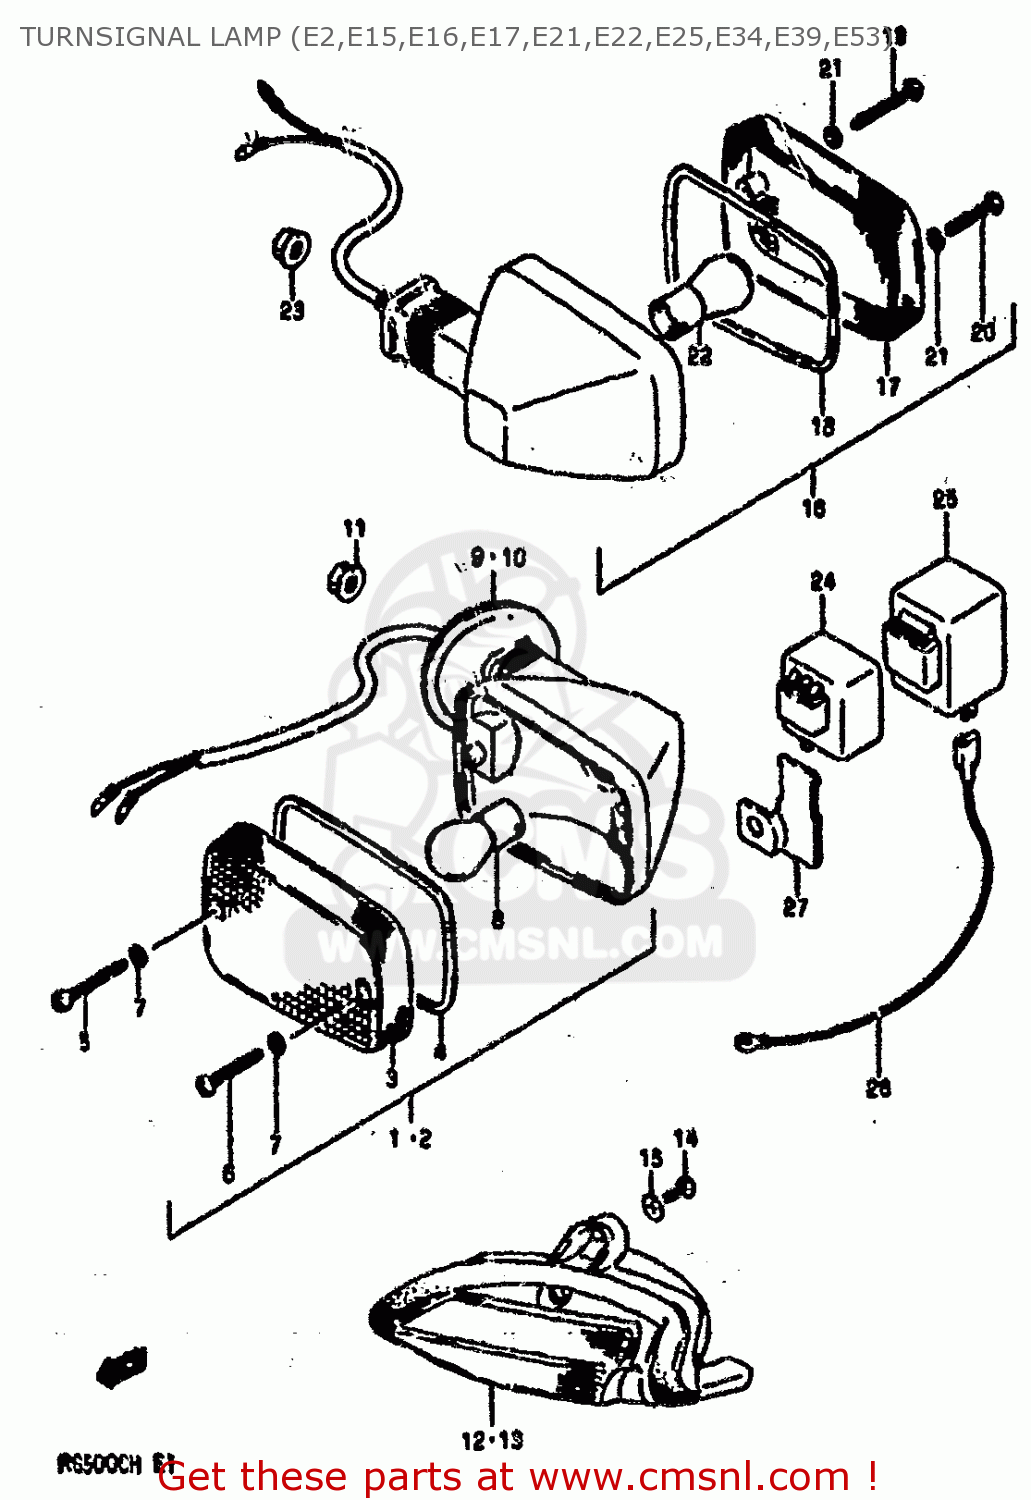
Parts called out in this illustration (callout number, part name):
1	LAMP,FRONT TURNSIGNAL
2	LAMP,FRONT TURNSIGNAL LH
3	LENS,FR
4	GASKET (NAS)
5	SCREW,TURN SIG LENS FITTING
6	SCREW
7	GASKET (NAS)
8	BULB(12V21W)
9	GROMMET,RH
10	GROMMET,LH
11	NUT
12	COVER,RH
13	COVER,LH
14	SCREW
15	WASHER
16	LAMP ASSY,RR
17	LENS,RR
18	GASKET (NAS)
19	SCREW,TURN SIG LENS FITTING
20	SCREW
21	GASKET (NAS)
22	BULB(12V21W)
23	NUT
24	RELAY ASSEMBLY,TURN SIGNAL
25	RELAY ASSY,TUR
26	WIRE,RELAY EARTH
27	BRACKET,TURN SIGNAL RELAY
